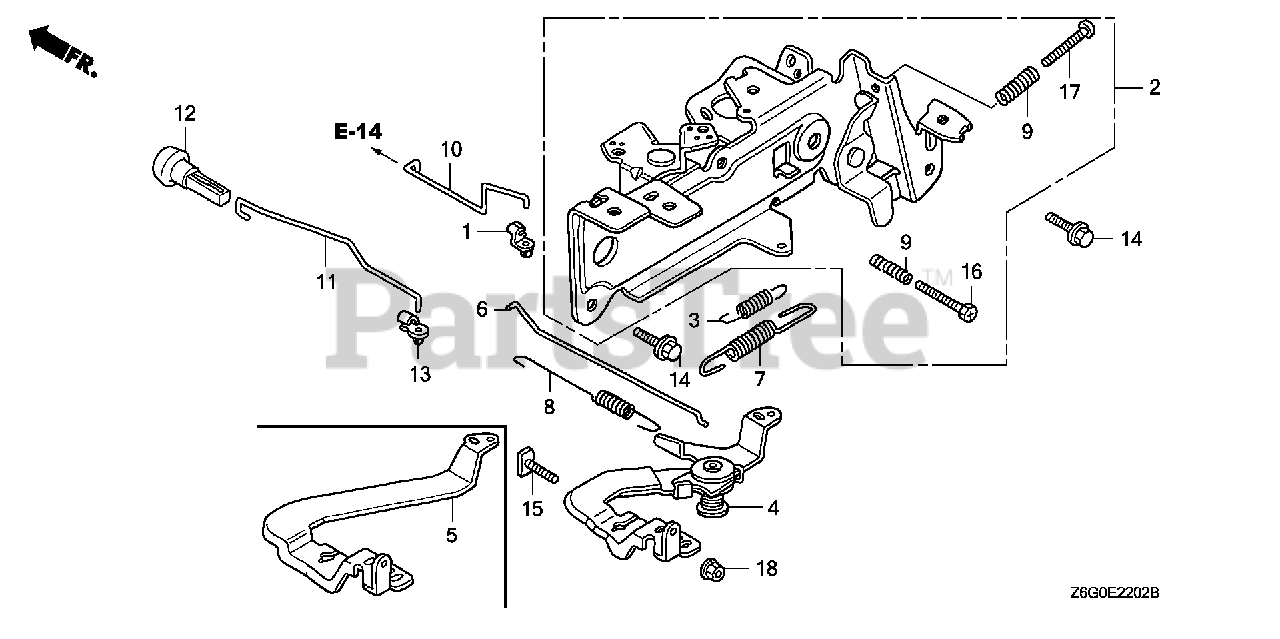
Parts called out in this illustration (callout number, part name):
1	JOINT, ROD
2	CONTROL ASSY. (AUTO THROTTLE)
3	SPRING, STARTER
4	ARM, GOVERNOR
6	ROD, GOVERNOR
7	SPRING, GOVERNOR (MANUAL)
8	SPRING, THROTTLE RETURN
9	SPRING, CONTROL ADJUSTING
10	ROD, CHOKE CONTROL
11	ROD, CHOKE KNOB
12	KNOB, CHOKE
13	BUSH, LINKAGE
14	BOLT, FLANGE (6X14) (CT200)
15	BOLT, GOVERNOR ARM
16	BOLT, RECESSED (5X25)
17	SCREW, PAN (5X35)
18	NUT, FLANGE (6MM)
